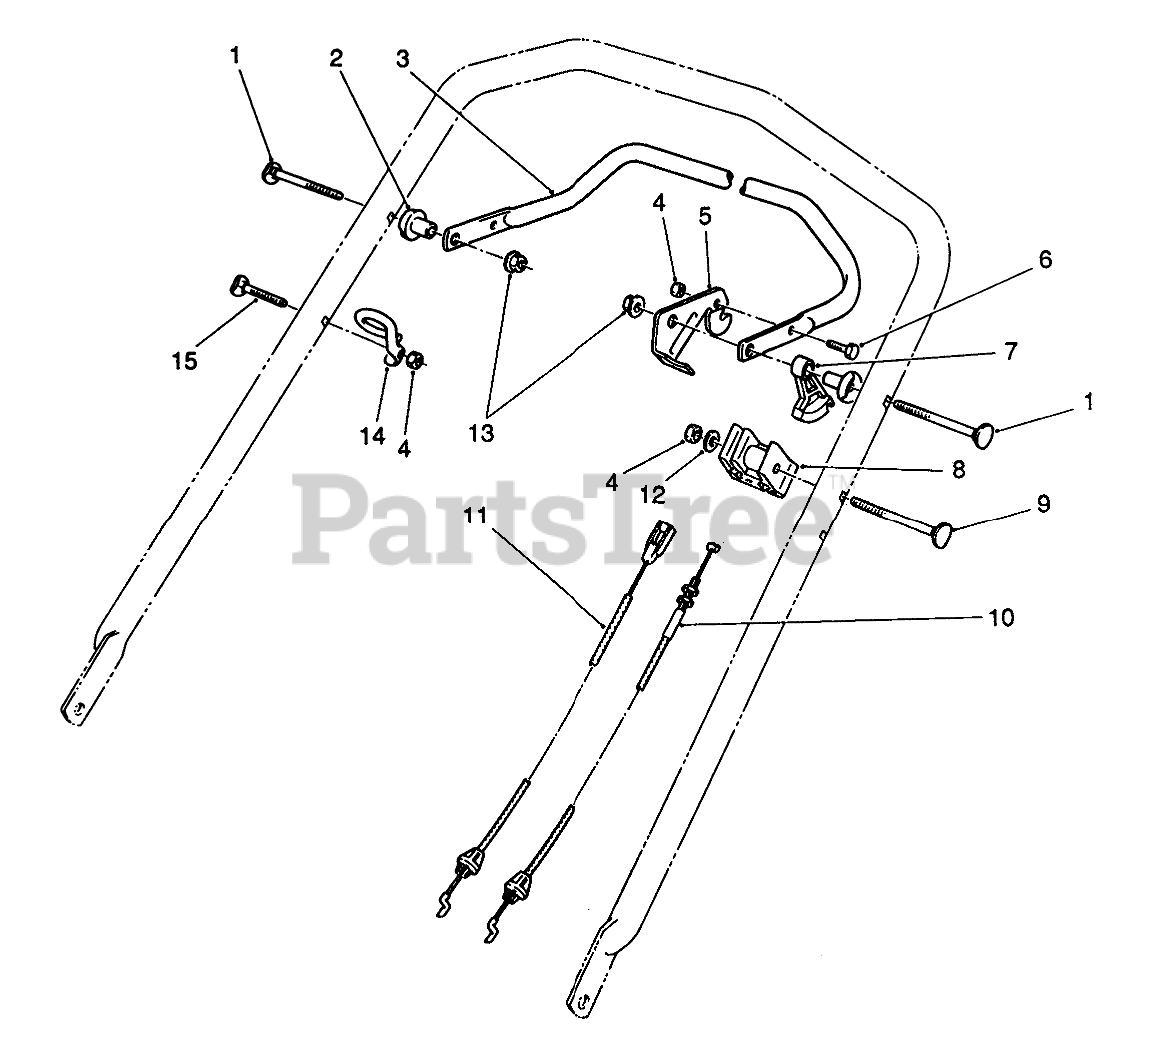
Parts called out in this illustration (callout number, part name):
1	SCREW-HANDLE
2	SPACER-SUPPORT
3	Bar-Control
4	NUT-LOCK, NI
5	LEVER-CONTROL
6	SCREW-HH
7	LEVER-TRACTION
8	SUPPORT-CABLE
9	SCREW-HANDLE
10	TRACTION CABLE
11	BRAKE CABLE
12	WASHER-FLAT
13	NUT-LOCK, NI
14	GUIDE-ROPE
15	Screw-Handle
